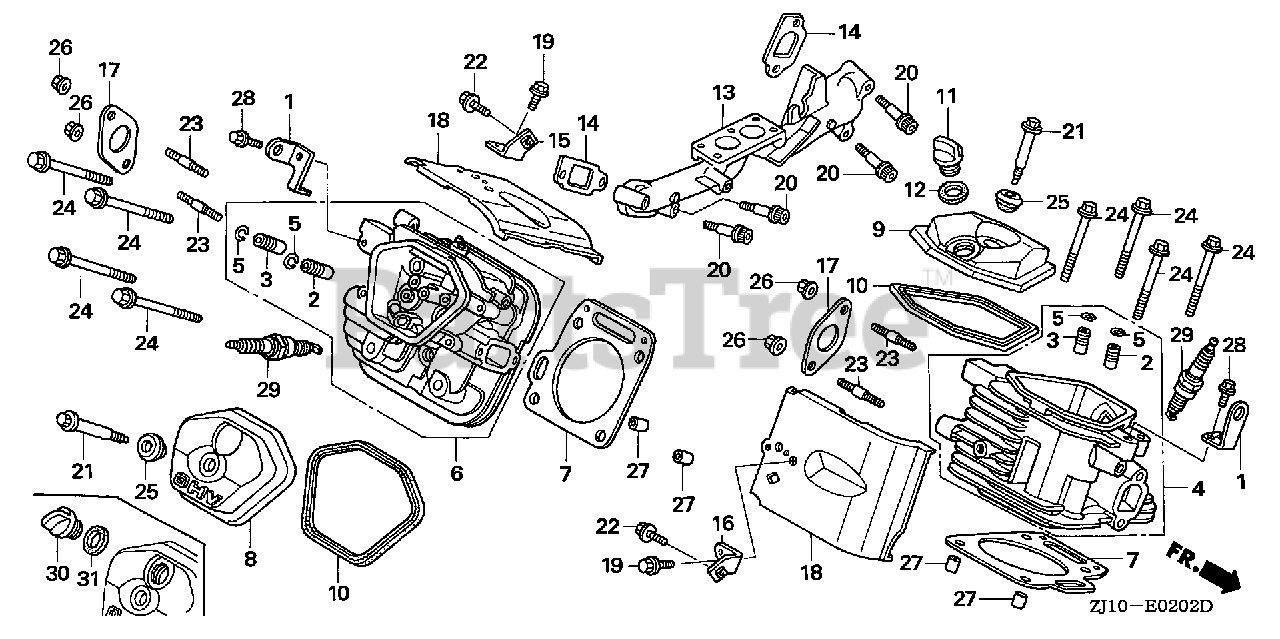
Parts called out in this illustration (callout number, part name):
1	HANGER, ENGINE
2	GUIDE, VALVE (OVER SIZE)
3	GUIDE, EX. VALVE (OVER SIZE)
4	CYLINDER HEAD (#1)
5	CLIP, VALVE GUIDE
6	CYLINDER HEAD (#2)
7	GASKET, CYLINDER HEAD
8	COVER, HEAD FILLER
9	COVER, HEAD
10	GASKET, HEAD COVER
13	MANIFOLD, IN.
14	GASKET, IN. MANIFOLD
15	BRACKET, R. AIR CLEANER
16	BRACKET, L. AIR CLEANER
17	GASKET, EX. PIPE
18	SHROUD, HEAD
19	BOLT, FLANGE (6MM)
20	BOLT, SOCKET (8X45)
21	BOLT, HEAD COVER
22	BOLT, FLANGE (6X14) (CT200)
23	BOLT, STUD (8X22)
24	BOLT, FLANGE (10X81)
25	WASHER, HEAD COVER
26	NUT, FLANGE (8MM)
27	PIN, DOWEL (12X20)
28	BOLT, FLANGE (8X20)
29	SPARK PLUG (ZGR5A-4)
30	CAP, OIL FILLER
31	GASKET, OIL FILLER CAP
